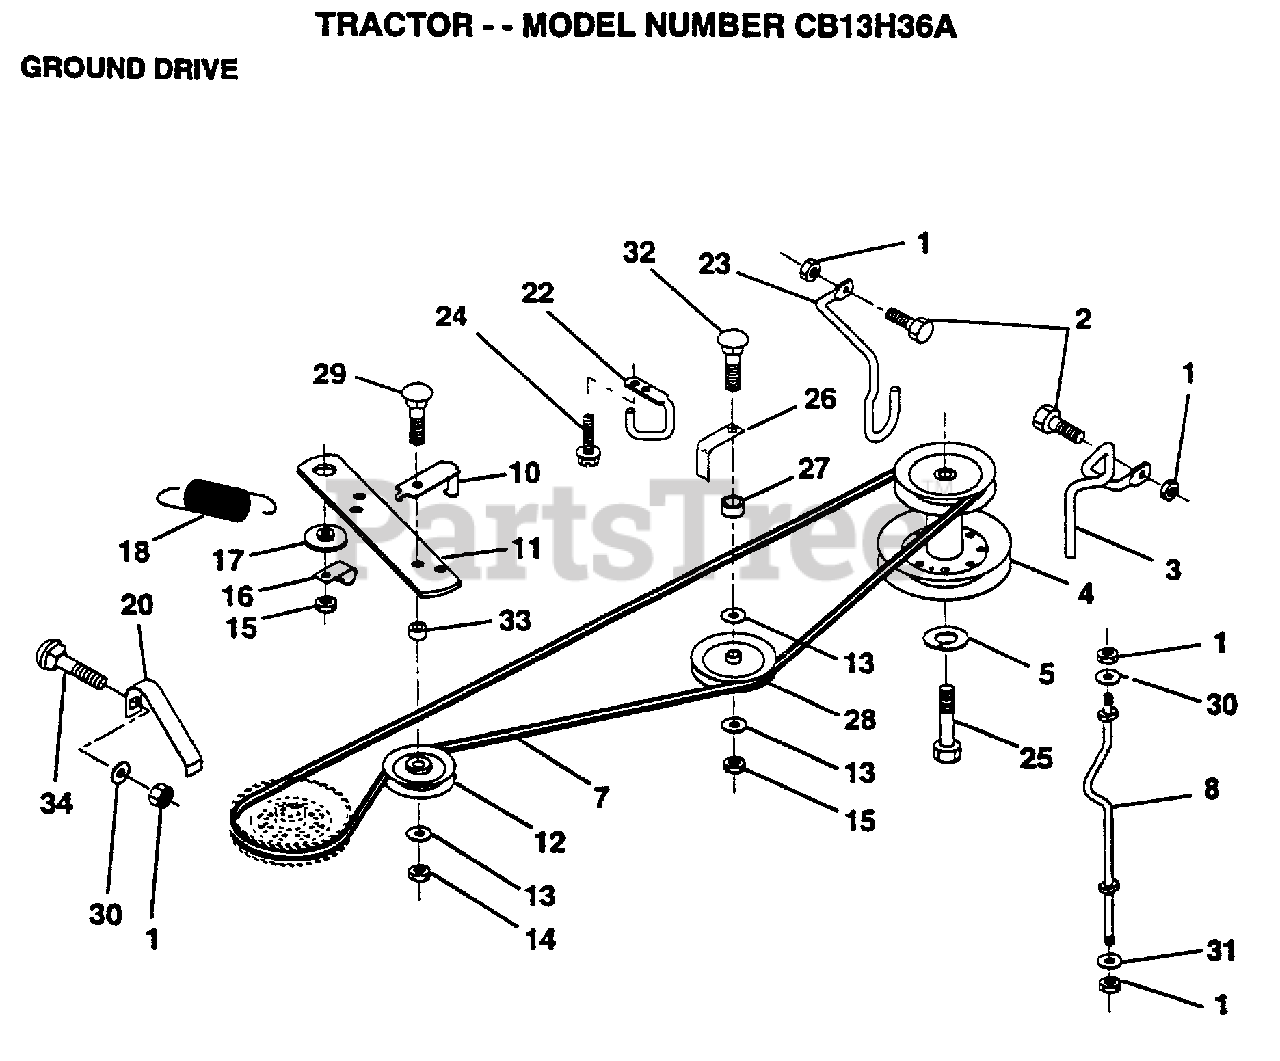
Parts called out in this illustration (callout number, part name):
1	NUT
2	BOLT
3	KEEPER.BELT.FRT.
4	PULLEY.ENGINE.LR
5	LOCKWASHER
7	BELT-V.DRV.77.75
8	KEEPER.BELT.HYDRO
10	KEEPER.BELT.GRD.
11	ARM IDLER CLUT GD
12	PULLEY.IDLER.FLAT
13	WASHER
14	LOCKNUT
16	"CLIP,INSULATOR"
17	SPACER RETAINER
20	KEEPER.BELT.LH
22	"KEEPER,FRA DR BEL"
23	KEEPER MOWER LH
24	SCREW
25	HEX BOLT
26	KEEPER.BELT.IDLER
27	SPACER.625X.843
28	PULLEY.IDLER.V.GR
29	BOLT RDHD 3/8-16
30	WASHER
31	WASHER M
32	BOLT
34	BOLT
